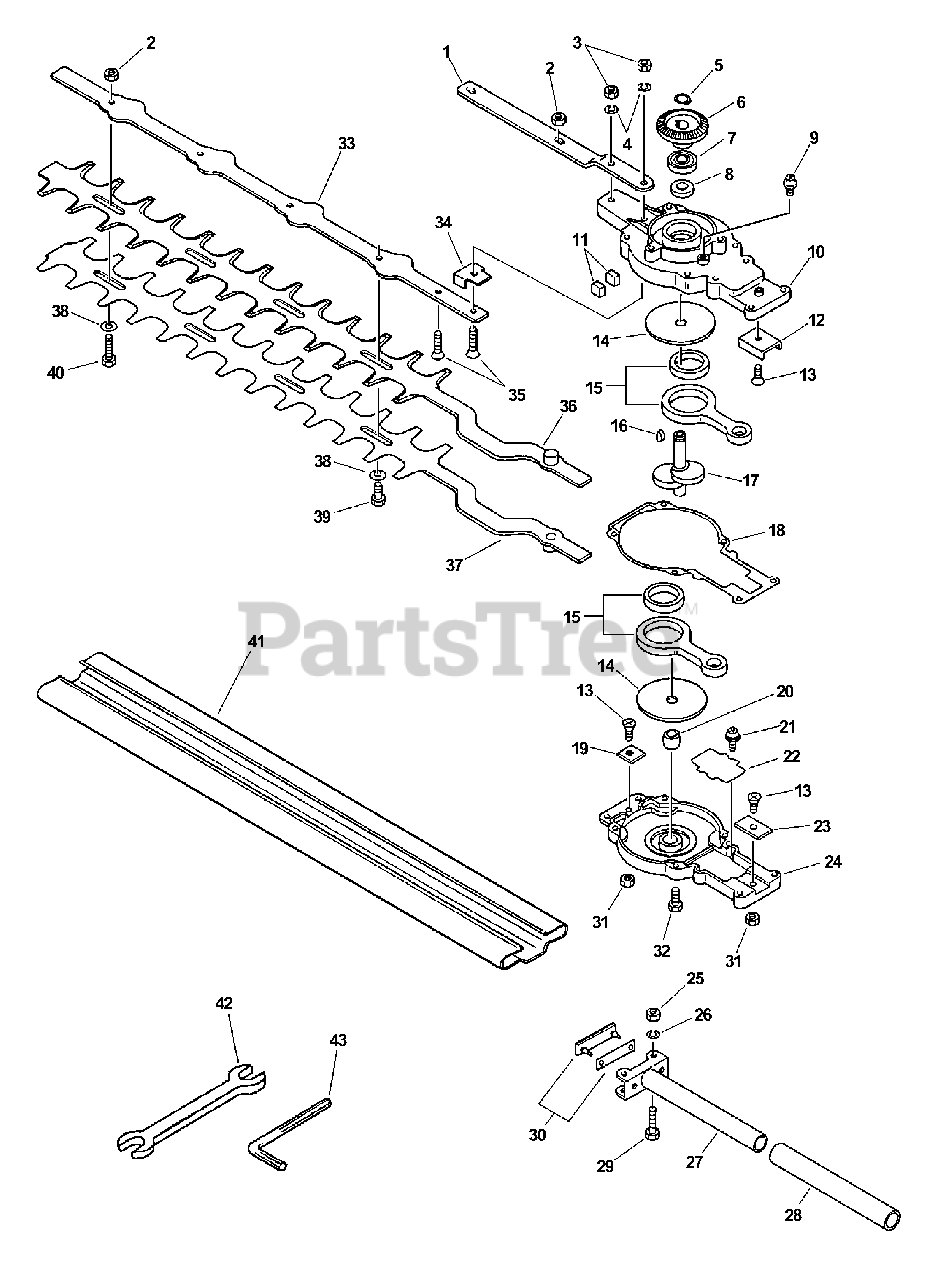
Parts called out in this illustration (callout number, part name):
1	SUPPORT, BLADE
2	LOCKNUT - 6
4	LOCKWASHER - 5
5	RING, RETAINING - 10
6	GEAR - SPUR
7	BEARING, BALL - 6000
8	SEAL, OIL
9	FITTING, GREASE
10	CASE, GEAR
11	SEAL, FELT
13	SCREW - 4X8
14	PLATE, SIDE
15	ROD, CONNECTING
18	GASKET, GEAR CASE
19	PLATE, GUIDE
20	BEARING, PLAIN
21	SCREW - 3X6
22	PLATE, SIDE
24	LID, GEAR CASE
26	LOCKWASHER - 5
28	GRIP, HANDLE
29	BOLT - 5X25
30	SPACER KIT
32	BOLT - 5X20
33	SUPPORT, BLADE
34	PLATE, ANGLE
35	SCREW - 5X20
36	BLADE - "TB" -- UPPER
37	BLADE - "BB" -- LOWER
38	WASHER - 6
39	BOLT - 6X22
41	COVER, BLADE
42	HEX KEY - 4mm
43	SPANNER - 8X10mm
